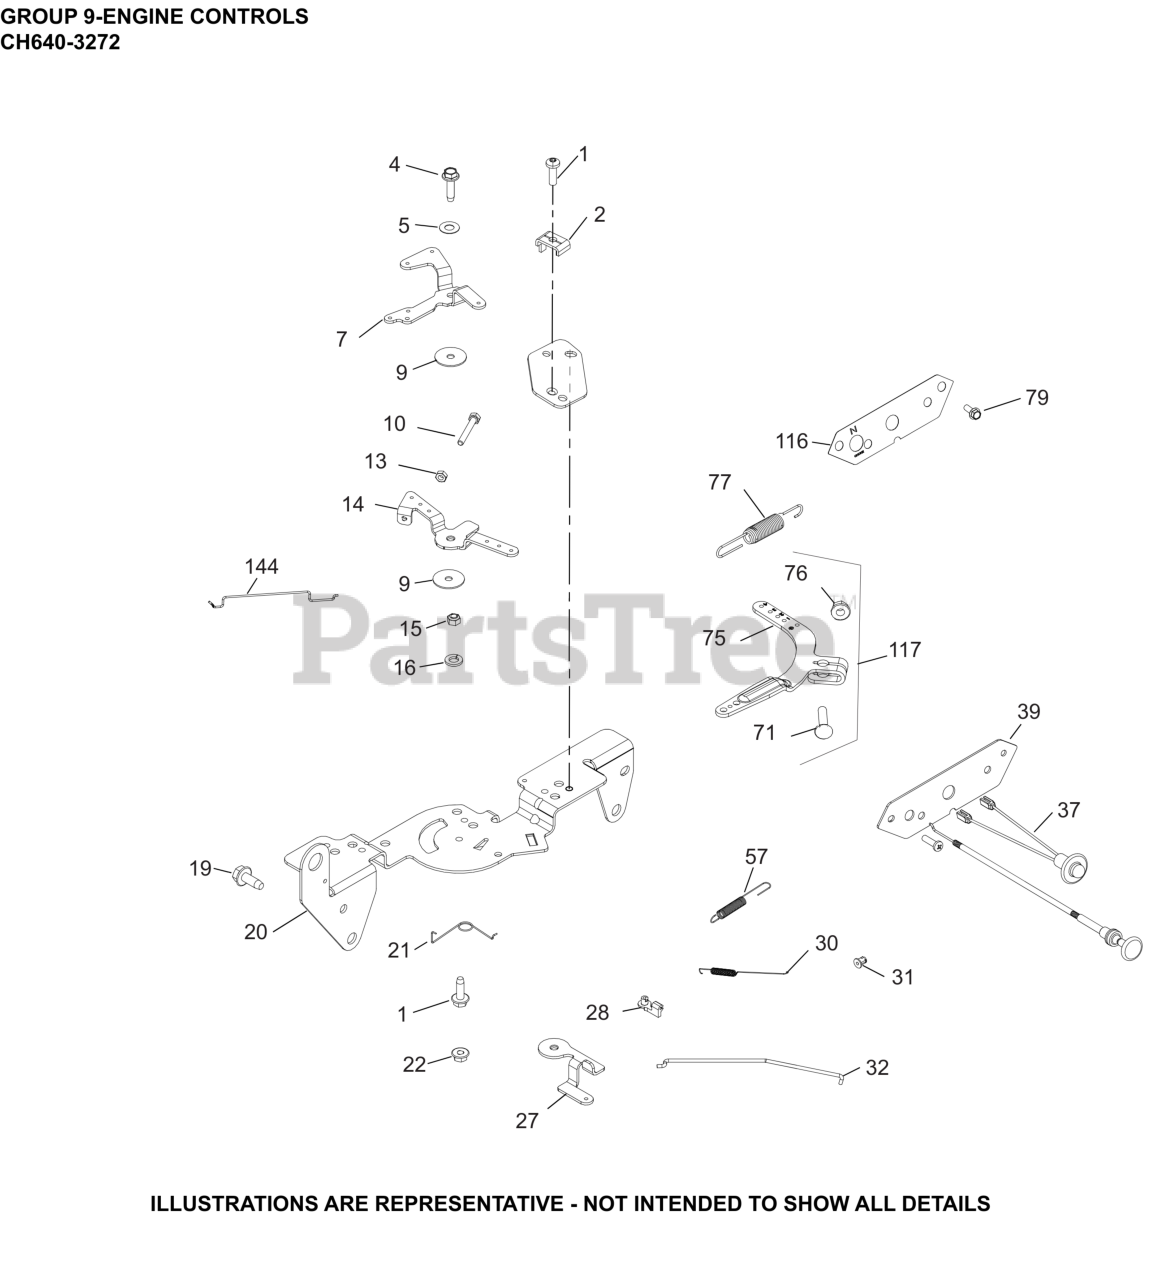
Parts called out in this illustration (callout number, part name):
1	SCREW, THREAD FORMING
2	CLAMP, CABLE CABLE
4	SCREW, THD FRM-USE 25 086 473-S
5	WASHER, SPRING 1/4"
7	LEVER, CHOKE
9	WASHER, FLAT 5.5 MM
10	SCREW, CAP M4X.7X30
13	NUT, M4X0.7
14	LEVER, THROTTLE CONTROL
15	NUT, FLG M5X.8
16	WASHER, SPRING LOCK 1/4"
19	SCREW, THREAD FORMING
20	BRACKET, CONTROL
21	SPRING, CHOKE RETURN
22	NUT, LOCK M5X.8
27	LEVER, THROTTLE ACTUATOR
28	BUSHING, THROTTLE LINKAGE
30	SPRING, LINKAGE
31	BUSHING, LINKAGE RETAINING
32	LINKAGE, THROTTLE
37	LIGHT, INDICATOR
39	PANEL, FRONT CONTROL
57	SPRING, THROTTLE LIMITER
71	BOLT, RD HD SQ NECK M6X1.0X25
75	LEVER, GOVERNOR - (#2409069S)
76	NUT, FLG M6X1.0
77	SPRING, GOVERNOR (BLUE)
79	SCREW, HI-LOW
116	DECAL, CONTROL PANEL
117	LEVER, GOVERNOR ASSEMBLY
144	LINKAGE, CHOKE
